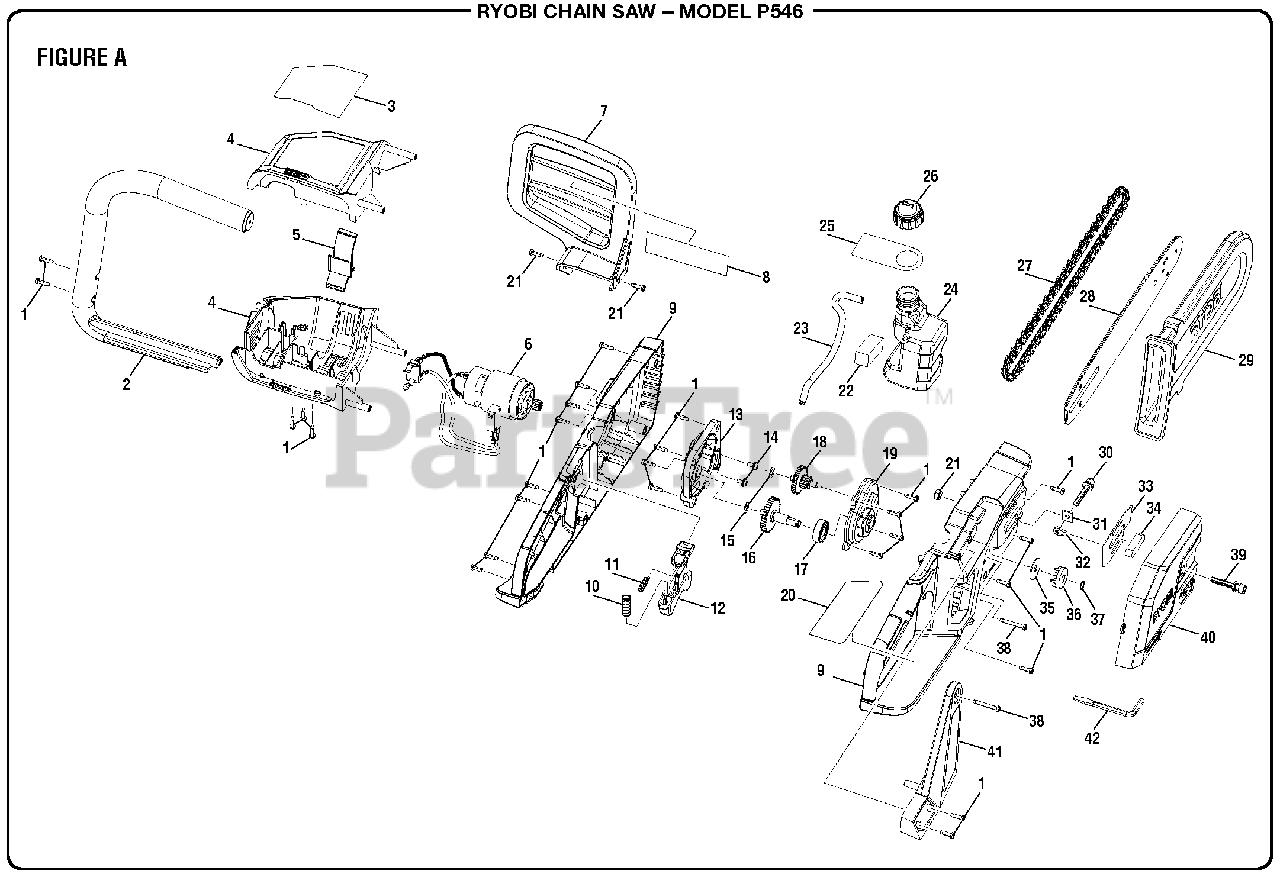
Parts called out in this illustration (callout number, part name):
1	Screw (M4 x 14 mm)
2	Front Handle
3	Warning Label
4	Motor Housing Assembly
5	Wind Plate
6	Motor and Wiring Harness Assembly
7	Front Handle Guard
8	Icon Warning Label
9	Housing Assembly
10	Compression Spring
11	Compression Spring
12	Trigger Assembly
13	Gear Box Base Assembly
14	Screw (M4 x 8 mm)
15	Washer (ID6.5 x OD13 x 0.5t)
16	Output Gear and Shaft Assembly
17	Ball Bearing (6000 2RS)
18	Input Gear Assembly
19	Gear Box Cover Assembly
20	Data and Warning Label
21	Screw (M4 x 14 mm, Tamper Proof)
23	Outlet Tube
25	Oil Cap Hang Tag
26	Oil Cap Assembly
27	Saw Chain
28	Guide Bar
30	Screw w/Washer (M5 x 30 mm, Rd. Hd.)
31	Insert Plate
32	Adjustment Block
33	Rubber Gasket
35	Cover Plate (Internal "D" Washer)
37	Retaining Ring
38	Screw (M4 x 30 mm)
39	Screw w/Washer (M6 x 35 mm, Soc. Hd.)
40	Bar Cover
41	Front Handle Arm
42	Combination Hex Key (5 mm x 10 mm Slotted)
